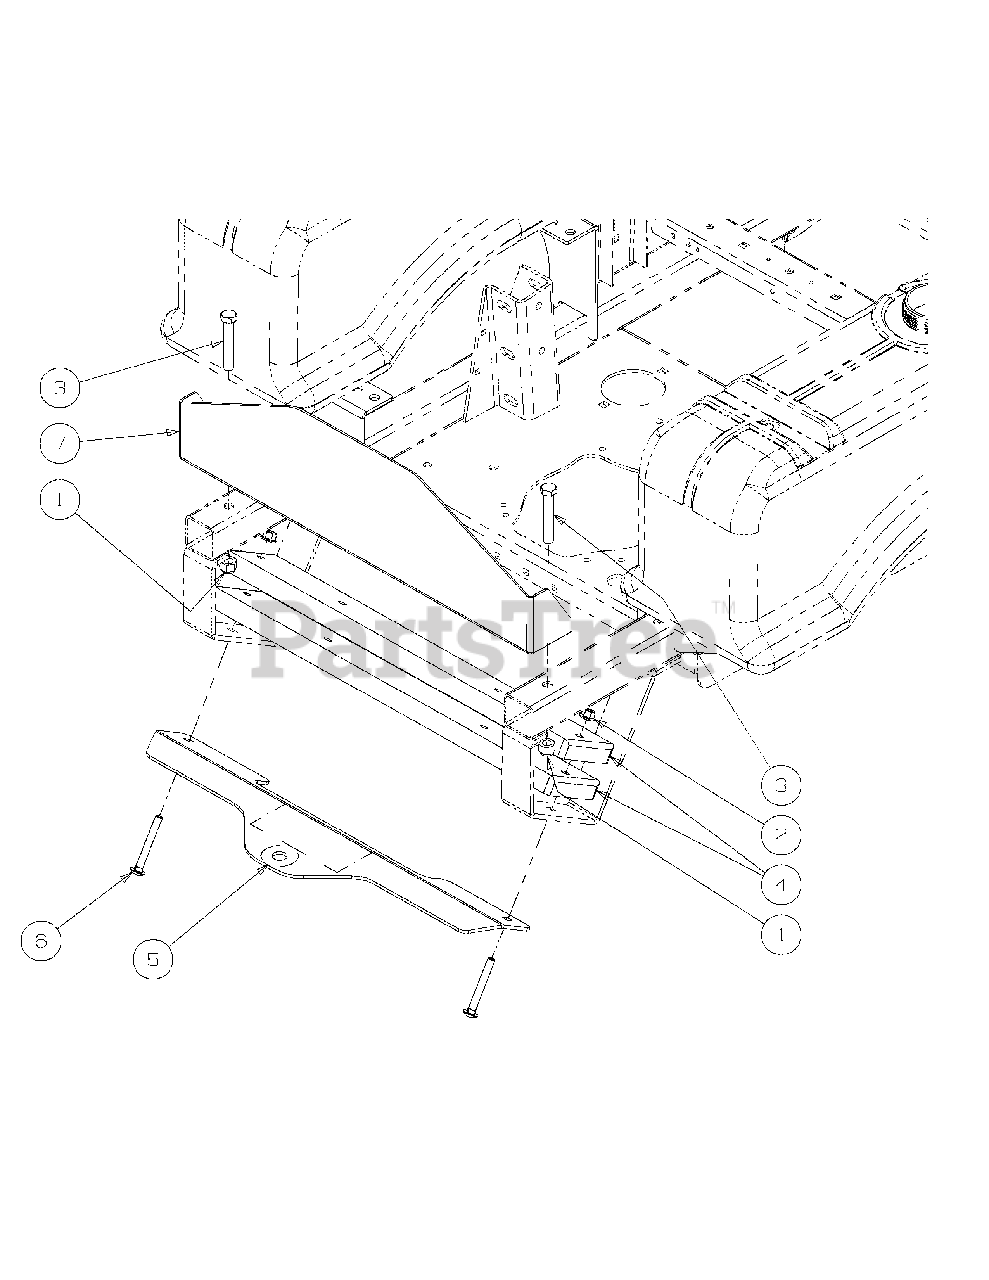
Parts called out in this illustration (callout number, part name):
1	Hex Nut, 1/2-13, Insert Lock
2	Nut, Hex 3/8-16 Flange Lock
3	HHCS, 1/2-13, 3.00
4	Bar, Weight
5	Hitch Bracket
6	Carriage Bolt, 3/8-16 x 3.00
7	Rear Bumper
